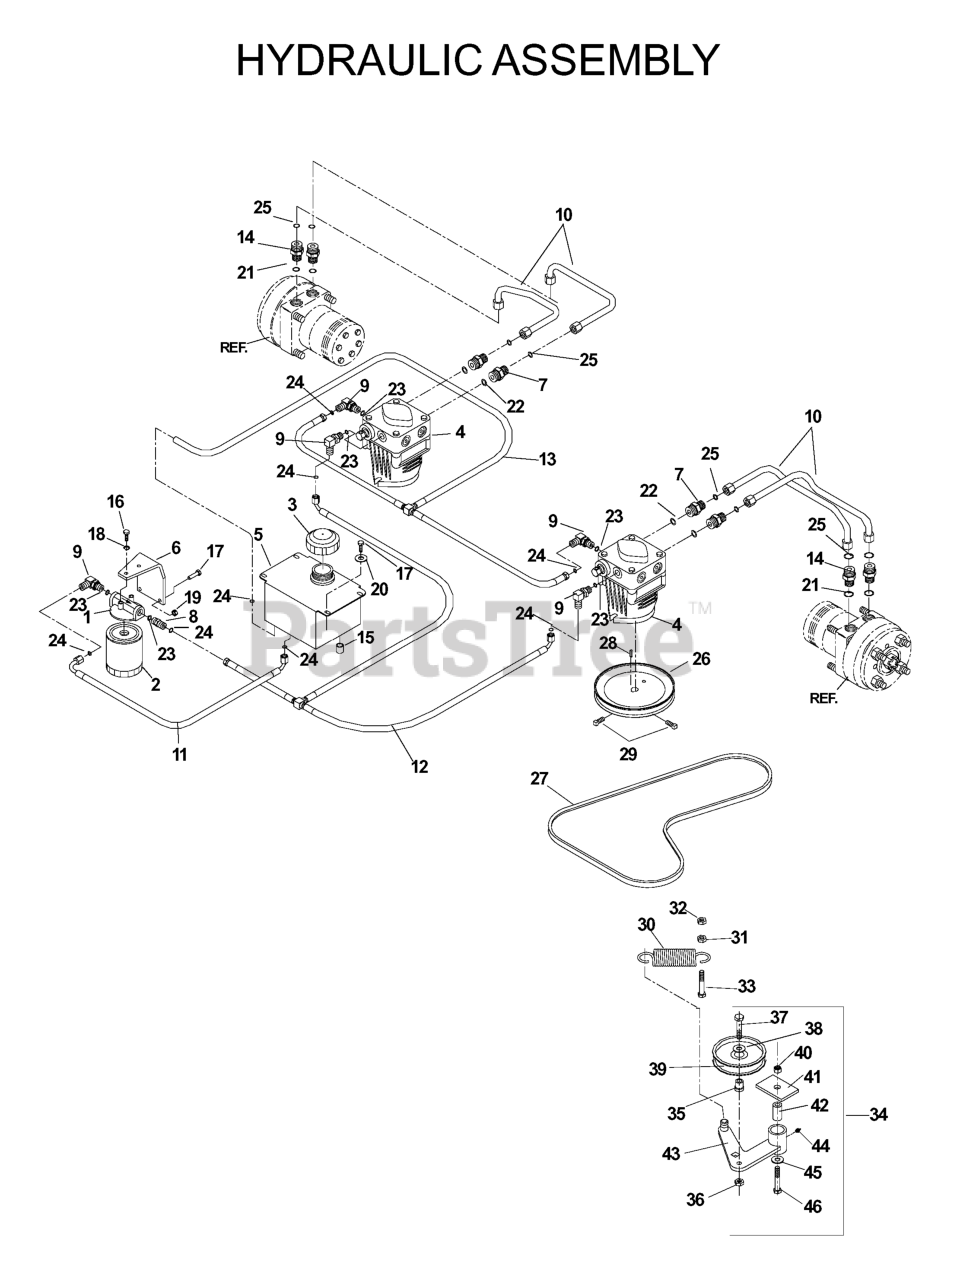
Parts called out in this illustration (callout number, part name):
1	FILTER HEAD
2	HYDRAULIC OIL FILTER
3	HYDRAULIC CAP
4	PUMP
6	OIL FILTER BRKT
7	FITTING, STRAIGHT F6400-8-8-0
8	STRAIGHT FITG
9	ELBOW, F6801-6-6-0 90 DEGREE
10	HYDRAULIC HOSE
12	TEE ASSEMBLY
13	TEE ASSEMBLY
15	NUT 9/16-18 JIC CAP
16	HCS 1/4C X 5/8
17	HCS 1/4C X 3/4 HCS
18	LOCKWASHER 1/4"
19	NUT.1/4-20.HEX.NYLOC.ZD
20	WASHER 1/4 FLAT
27	PUMP BELT
28	KEY 5 MM SQ X 25 MM
29	SCREW 5/16C X 5/8 SQ HEAD
31	NUT 3/8C WHIZ
32	NUT 3/8-16 NYLOC
33	HCS 3/8C X 2
34	IDLER ARM ASM
35	BUSHING, IDLER FLANGE
36	NUT 3/8C CENTERBLOCK
37	HCS 3/8-16 X 1 3/4 GR5
38	WASHER 3/8 FLAT
39	IDLER PULLEY
40	NUT 1/2-13 HEX NYLOC ZD
42	PIVOT BUSHING
43	IDLER ARM WLDT
44	ZERK
45	WASHER 1/2 FLAT
46	HCS 1/2C X 3 1/4
